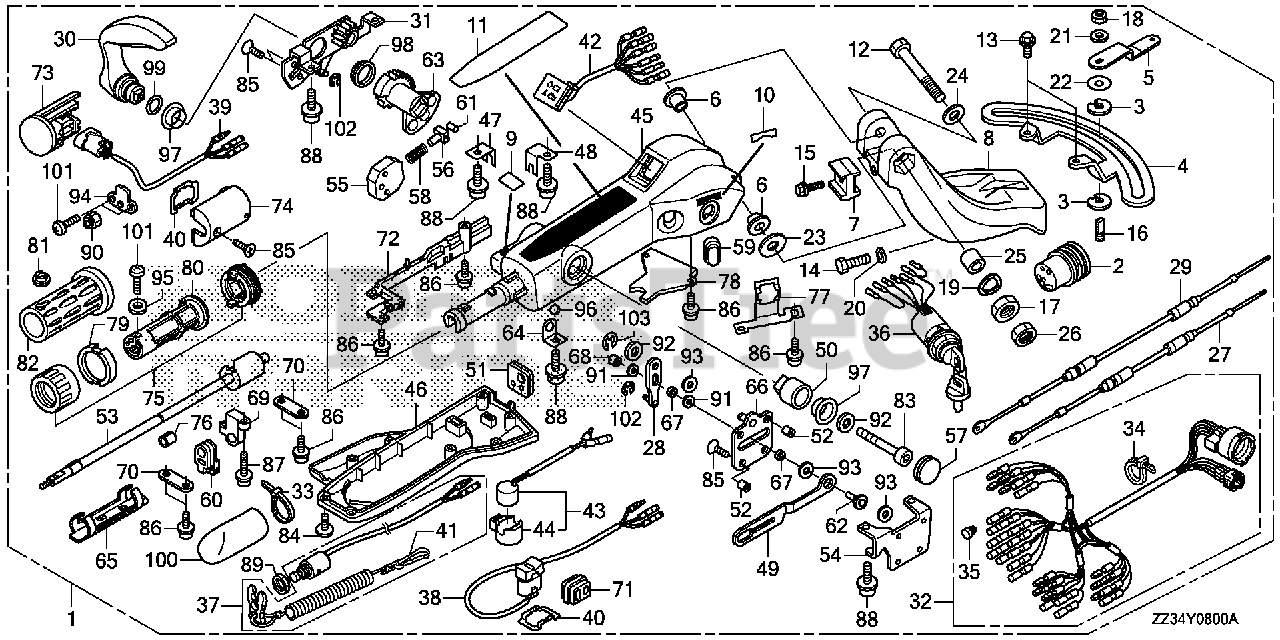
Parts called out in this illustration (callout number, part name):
1	HANDLEBAR KIT *NH282MU* (OYSTER SILVER METALLIC-U)
2	GROMMET, HANDLEBAR CABLE
3	BLOCK, FRICTION
4	PLATE, FRICTION
5	LEVER, FRICTION
6	BUSH, HANDLEBAR
7	BLOCK, HEIGHT ADJUSTER
8	BRACKET, STEERING *NH282MU* (OYSTER SILVER METALLIC-U)
9	MARK, EMERGENCY SWITCH INDICATION
9	MARK, EMERGENCY SWITCH INDICATION (EU)
10	MARK, START
11	MARK, HANDLEBAR
12	BOLT, HEX. (12X80)
13	BOLT, FLANGE (6X12)
14	BOLT, HEX. (10X32)
15	BOLT, FLANGE (8X28)
16	BOLT, STUD (8X26)
17	NUT, HEX. (12MM)
18	NUT, SELF-LOCK (8MM)
19	WASHER, WAVE (14MM)
20	WASHER (10MM)
21	WASHER (8MM)
22	WASHER, NYLON (8MM)
23	WASHER, PLAIN (12MM)
24	WASHER, PLAIN (12MM)
25	COLLAR, DISTANCE (12.2X23X16)
26	NUT, HEX. (12MM)
27	CABLE, THROTTLE
28	ARM ASSY., THROTTLE
29	CABLE, SHIFT
30	LEVER, SHIFT
31	FRAME ASSY., SHIFT
32	CABLE ASSY. A, LONG HANDLE
33	BAND (CONVEX CV-150)
34	BAND (CONVEX CV-200)
35	PLUG, CONNECTOR (INNER)
36	SWITCH ASSY., COMBINATION
37	SWITCH ASSY., EMERGENCY STOP
38	SWITCH ASSY., TROLLING CONTROL
39	SWITCH ASSY., POWER TILT
40	PLATE, SWITCH
41	WIRE, EMERGENCY
42	LAMP ASSY., INDICATOR
43	BUZZER ASSY., WARNING
44	SUSPENSION, WARNING BUZZER
45	HOUSING *NH282MU* (OYSTER SILVER METALLIC-U)
46	COVER (LOWER)
47	CLAMP, SHIFT CABLE
48	CLAMP, THROTTLE CABLE
49	PLATE, LOCK
50	STOPPER, SHIFT
51	GROMMET
52	SPACER
53	SHAFT ASSY., THROTTLE
54	FRAME, THROTTLE
55	GUIDE, SPRING
56	ACTUATOR
57	CAP
58	SPRING
59	GROMMET, POWER TILT SWITCH
60	GROMMET, POWER TILT SWITCH
61	ROLLER
62	PIN, SLIDE
63	GEAR, SHIFT
64	PLATE, BALL GUIDE
65	GUIDE, THROTTLE HARNESS
66	FRAME ASSY., THROTTLE SUB
67	ROLLER, PLATE
68	ROLLER, CAM
69	STAY
70	PLATE, SHIFT CLAMP
71	GROMMET, SIDE
72	GUIDE, HARNESS
73	BOX ASSY., POWER TILT SWITCH (1)
74	BOX ASSY., POWER TILT SWITCH (2)
75	GRIP ASSY., THROTTLE FRICTION
76	BUSH, THROTTLE SHAFT
77	HOLDER, SWITCH
78	PLATE, HARNESS
79	PAD, THROTTLE FRICTION
80	PIPE, THROTTLE GRIP
81	CAP, GRIP
82	RUBBER, GRIP
83	BOLT, SOCKET (8X70)
84	BOLT (M5X12)
85	SCREW, FLAT (5X14)
86	BOLT (5X12)
87	BOLT (5X20)
88	BOLT (6X15)
89	NUT, HEX. (16MM)
90	NUT, NYLON (5MM)
91	WASHER
92	WASHER (8MM)
93	WASHER
94	WASHER, PLATE
95	WASHER (5MM)
96	BALL, STEEL
97	BEARING
98	BEARING
99	O-RING (20.6X1.9)
100	TUBE, CORD (30MM)
101	SCREW, PAN (5X14)
102	E-RING (4MM)
103	E-RING (7MM)
